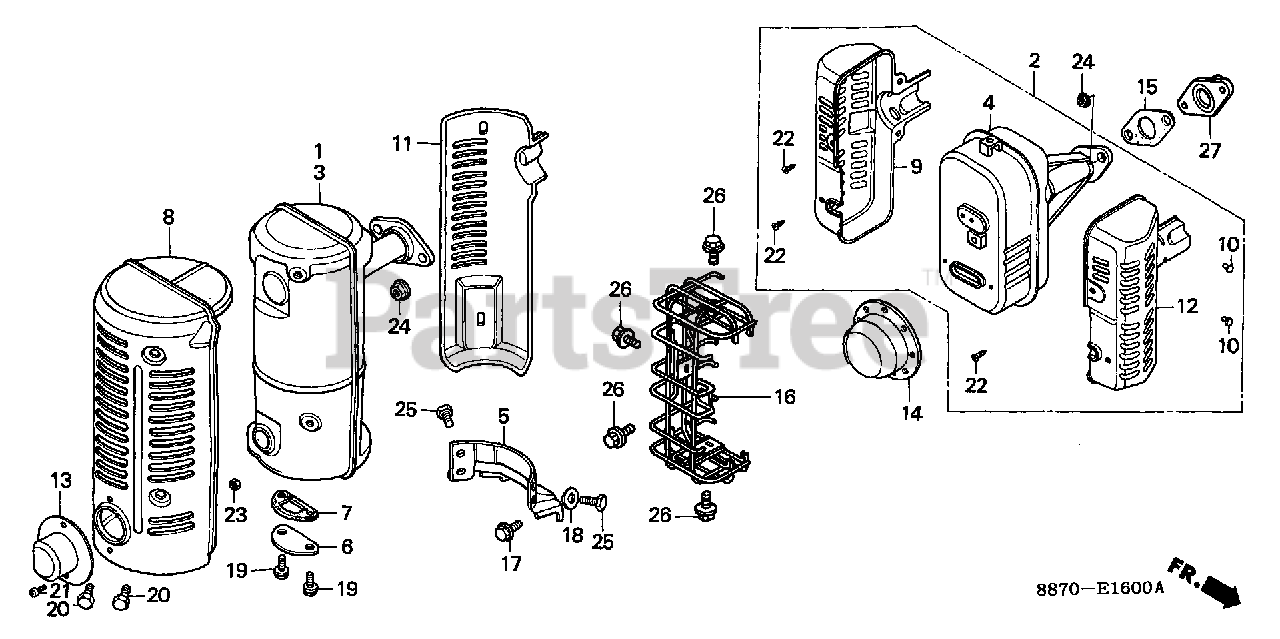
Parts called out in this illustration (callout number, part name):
1	MUFFLER (MUFFLER LID)
2	MUFFLER ASSY.
4	MUFFLER
5	STAY, MUFFLER
6	LID, MUFFLER
7	GASKET, MUFFLER LID
8	PROTECTOR A, MUFFLER
9	PROTECTOR, L. MUFFLER
10	RIVET (4X5)
11	PROTECTOR B, MUFFLER
12	PROTECTOR, R. MUFFLER
13	DEFLECTOR, EX. MUFFLER (NOT AVAILABLE)
14	CAP, MUFFLER
15	GASKET, MUFFLER
17	BOLT, FLANGE (8X16)
18	WASHER (23X8.3X3.2)
19	BOLT, HEX. (6X12)
20	BOLT, HEX. (6X6)
21	SCREW, PAN (4X6) Use from Engine SN 1246007.
22	SCREW, TAPPING (4X8)
22	SCREW, TAPPING (4X8) (NOT AVAILABLE)
23	NUT, HEX. (4MM) Use from Engine SN 1246007.
24	NUT, FLANGE (8MM)
25	BOLT, FLANGE (6X10)
